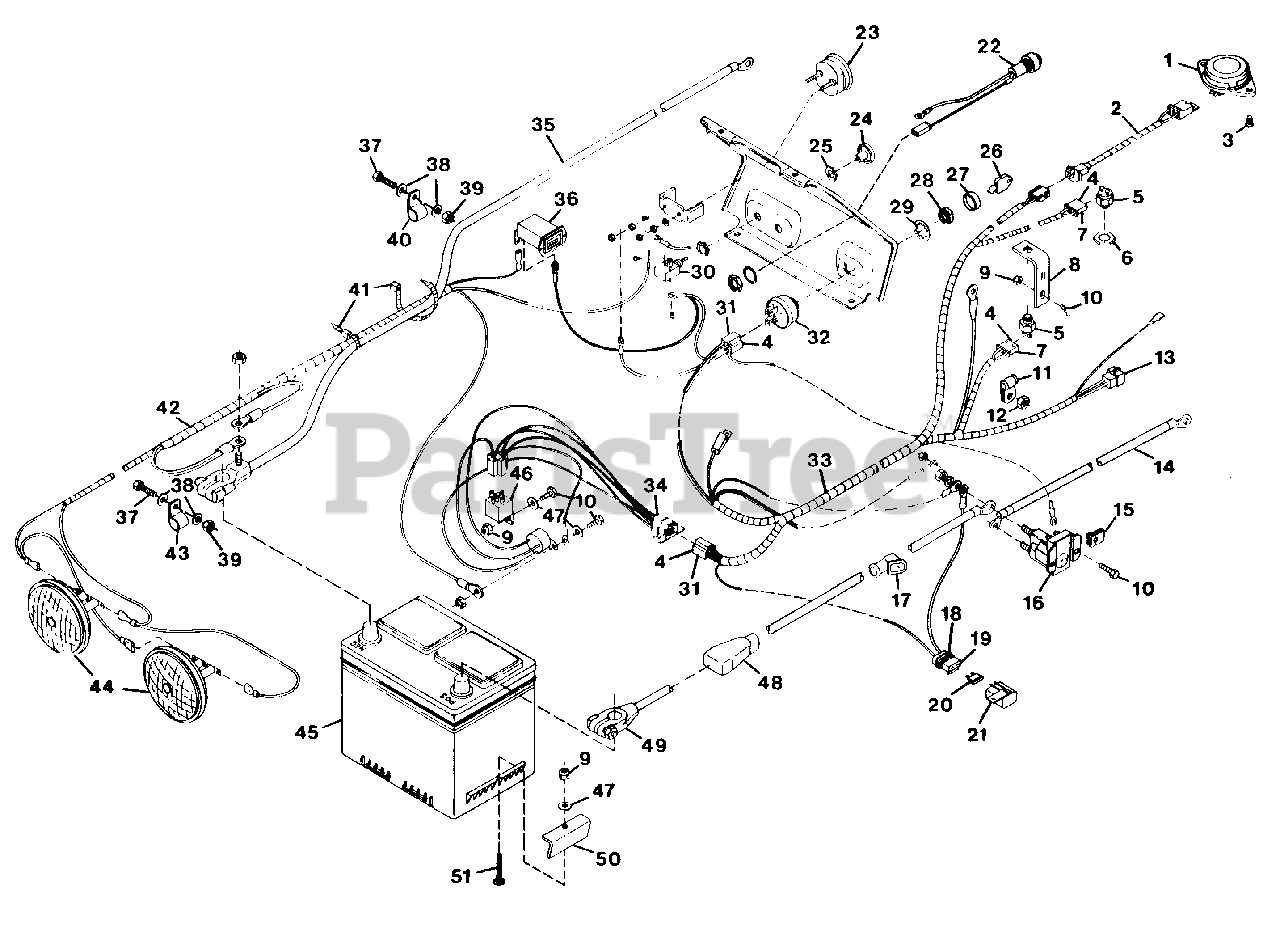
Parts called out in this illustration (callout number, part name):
1	SWITCH, SEAT
2	HARNESS, WIRING SEAT SWITCH
3	SCREW, MACHINE 1/4-20
4	TERMINAL
5	SWITCH, INTERLOCK
6	NUT, STAMPED 9/16-18
7	CONNECTOR, 2-WIRE SWITCH
8	BRACKET, SWITCH
9	NUT, LOCK 1/4-20
10	BOLT, HEX 1/4-20X.75
11	CLAMP
12	NUT, LOCK 3/8-16
13	CONNECTOR
14	CABLE, STARTER
15	NUT, SPEED 1/4-20
16	SWITCH, MAGNETIC
17	BOOT, BATTERY CABLE
18	CONNECTOR
19	TERMINAL, 14-16 GAUGE
20	FUSE, 25 AMP
21	COVER
22	LIGHT, INDICATOR
23	GAUGE, AMMETER
24	KNOB, LIGHT SWITCH
25	NUT, SPECIAL LIGHT SWITCH
26	KEY, IGNITION SWITCH
27	BOOT, 9/16 SWITCH
28	NUT, JAM 9/16-24
29	WASHER, LOCK 9/16 INT. TOOTH
30	SWITCH, LIGHT
31	CONNECTOR
32	SWITCH, IGNITION
33	HARNESS, WIRING
34	MODULE, TIME DELAY
35	CABLE, NEGATIVE BATTERY
36	HOURMETER
37	BOLT, HEX 5/16-18X1.00
38	WASHER, FLAT .344X.688X.065
39	NUT, LOCK 5/16-18
40	CLAMP, NYLON
41	TIE, CABLE
42	HARNESS, WIRING GROUND AND LIGHT
43	CLAMP, NYLON
44	HEADLIGHT
45	BATTERY, 12 VOLT
46	RELAY
47	WASHER, FLAT .281X.625X.065
48	COVER, BATTERY TERMINAL
49	CABLE, BATTERY TO MAGNETIC SWITCH
50	CLAMP
51	BOLT, 1/4-20X1.75 RD HD SQ NK
